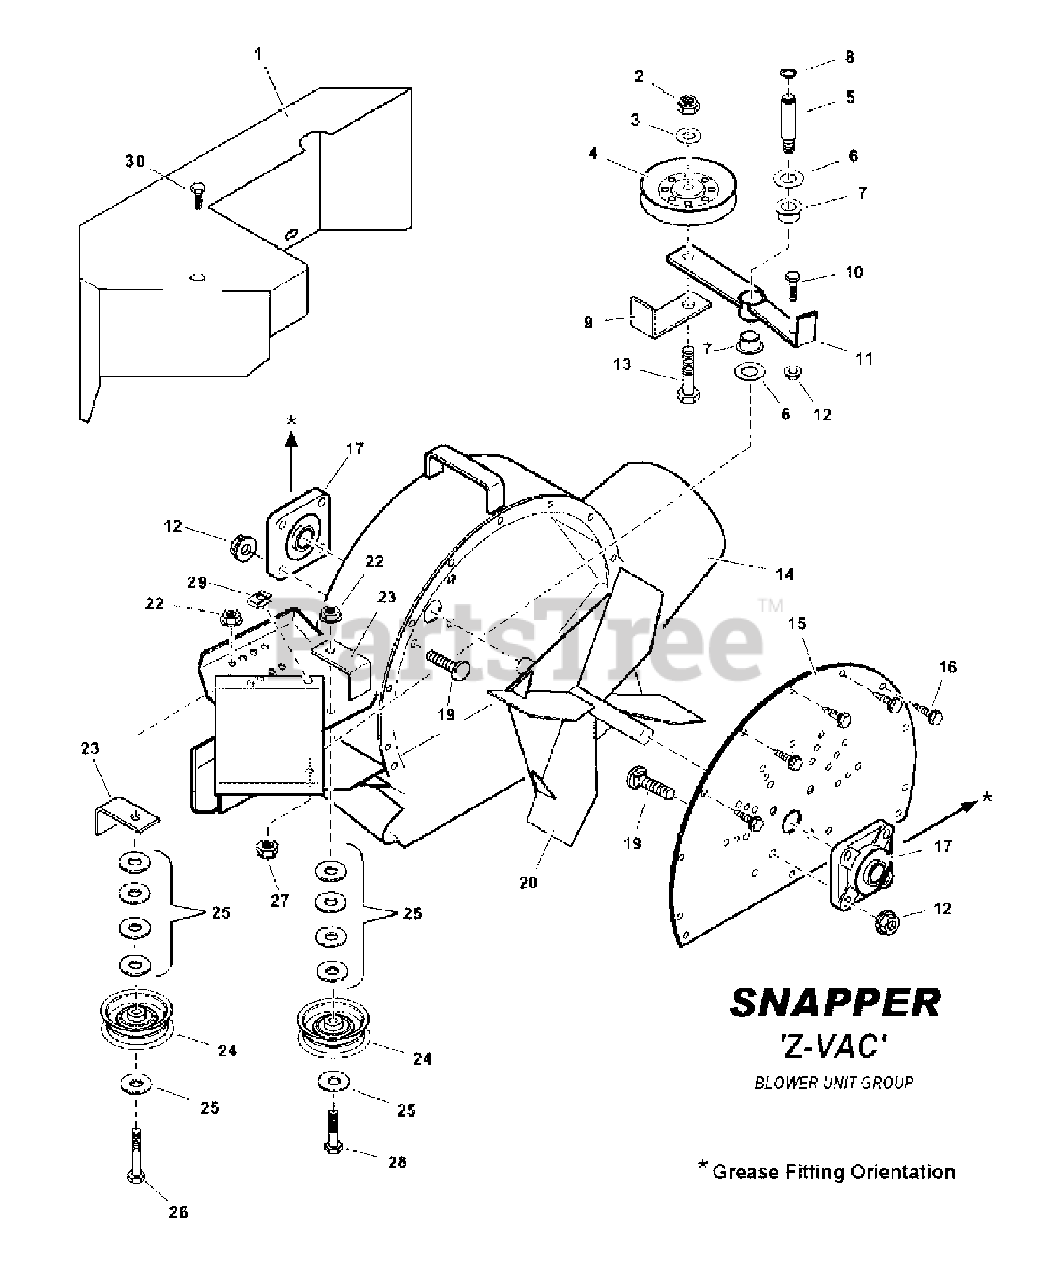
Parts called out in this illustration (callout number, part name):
1	BELT GUARD, Blower
2	NUT, Nylon Lock 1/2-13
3	WASHER,.66X1.31X.09
4	PULLEY, A Groove Idler, Steel
5	STUD, Idler
6	WASHER, Flat 9/16
7	BEARING, Flanged 9/16
8	RING, Retaining 1/2"", HD
9	IDLER, Belt Retainer
10	SCREW, Hex Head Cap 5/16-18 X 1.25 GR 5 YZ
11	WELDMENT, Idler Arm
12	NUT, Flange Lock,, 5/16-18 YZ
13	SCREW, Hex Head Cap 1/2UNC X 2.5"" (Black Phosphate)
14	WELDMENT, Blower Housing
15	BACK PLATE, Blower
16	SCREW, Hex Washer Self-Tap 5/16-18 X 3/4-YZ
17	BEARING, Flanged, 1" Bore
19	BOLT, Carriage Short Neck 5/16-18 X 3/4 GR5 YZ
20	IMPELLER, Fast-Vac BLOWER
22	NUT, Hex Flange Lock,, 3/8-16
23	RETAINER, Belt
24	PULLEY, Idler Flat
25	WASHER, SAE 3/8
26	SCREW, Hex Head Cap 3/8C X2-1/4 GR5 YZ
27	NUT, Hex Lock Nylon, 3/8F YZ
28	SCREW, Hex Head Cap 3/8-16 X 2 GR5 YZ
29	U-CLIP, 5/16-18
30	SCREW, Hex Washer Self-Tap 5/16-18 X 3/4-YZ
